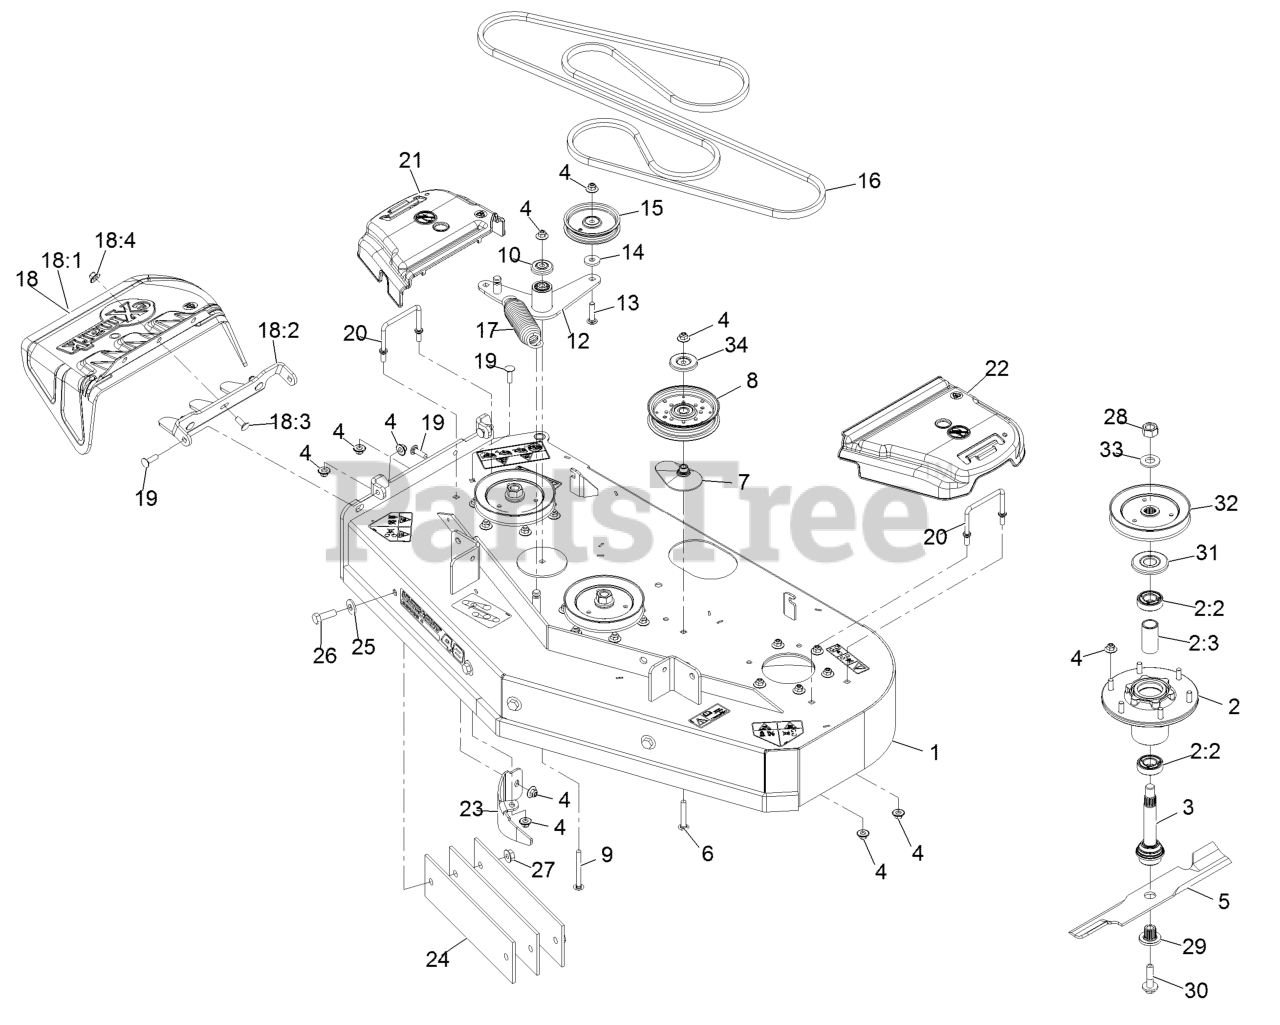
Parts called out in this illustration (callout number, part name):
1	Deck ASM-484
2	ASM-Cutter Hsg With Bearings
2:2	Bearing-Ball
2:3	Spacer-Bearing
3	ASM-Spindle And Seal
4	Nut-Nyloc 3/8-16 Flg
5	Blade-Notched
5	Blade-Extreme 2, 16.25"
5	Blade, Mulching
5	Blade, Low Lift
5	Blade, Solid
6	Bolt-Carriage 3/8-16 X 2 1/2
7	Spacer-Pulley
8	Idler-Pulley, Flat 5.00X0.95
9	Bolt-Carriage 3/8-16 X 3 1/2
10	Guard-Top
12	Idler Arm ASM W/Bearings
13	Bolt-Carriage 3/8-16 X 1 3/4
15	Pulley-Idler
16	V-Belt
17	Spring-Extension
18	ASM,Discharge Chute
18:1	Chute, Discharge
18:2	Bracket,Discharge Chute
18:3	Bolt-Carriage 3/8-16 X 1
18:4	Nut-Nyloc 3/8-16 Flg
19	Bolt-Carriage 3/8-16 X 1 1/4
20	Wireform-Cover
21	Cover-Belt, RH
22	Cover-Belt, LH
23	Baffle-Dogleg,Lzs Lzx Vt48
24	Bar,Weight
25	Washer-Spring Disc 1/2
26	Screw-HH 1/2-13 X 1 1/2
27	Nut-Whizlock 1/2-13
28	Nut-Hex
29	Bushing, Splined
30	Screw-Sems 1/2-20 X 2.19
31	Guard,Bearing Top .989
32	Sheave,Blade Drive 5.90
33	Washer-Spring Disc 3/4
34	Shield-Dust
